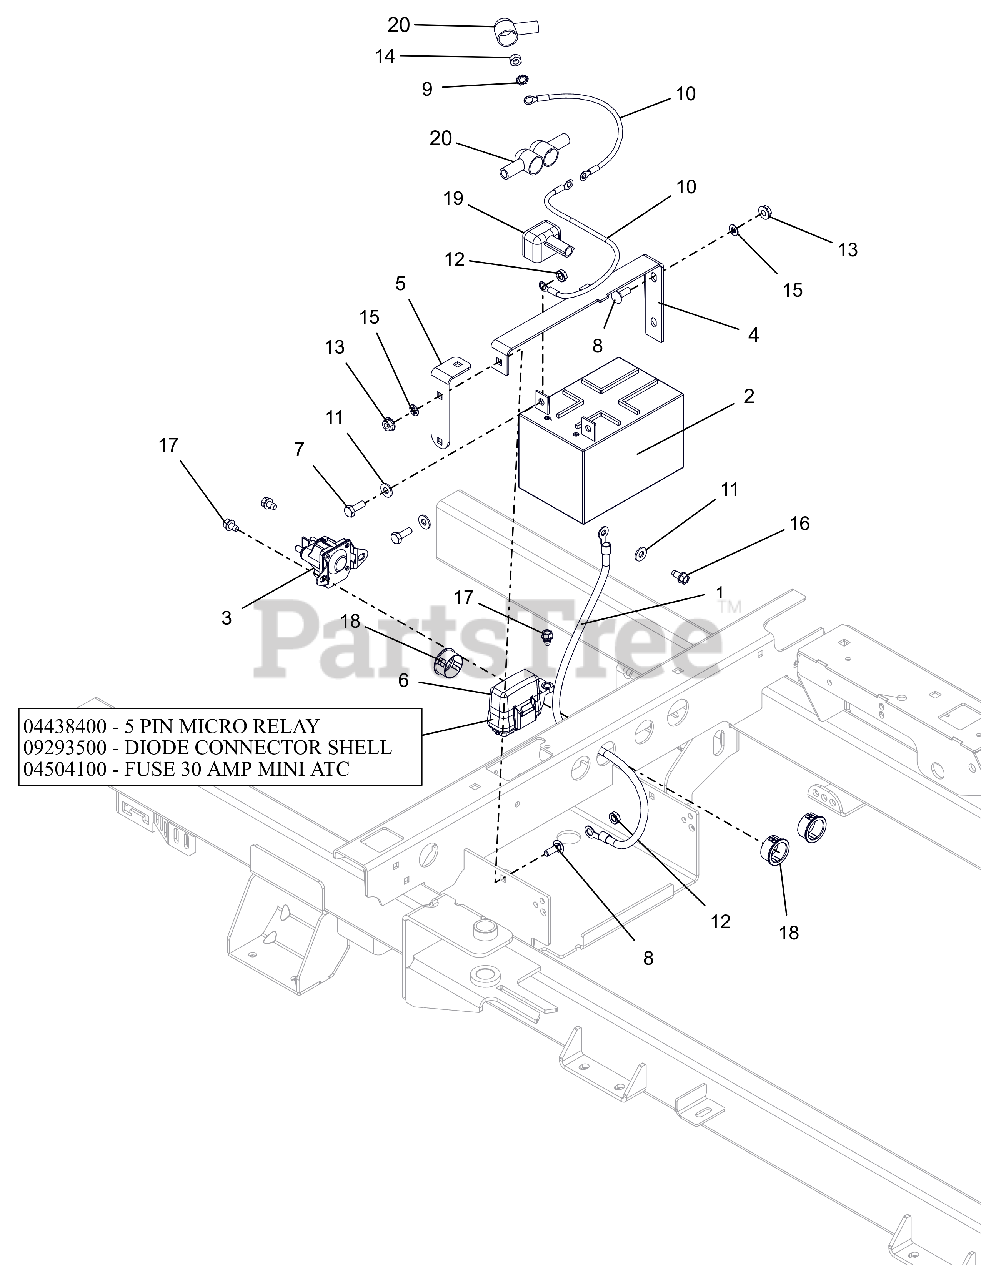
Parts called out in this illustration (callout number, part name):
1	CABLE-NEGATIVE BATTERY 24.00"
2	BATTERY, 12V 12A-190CCA
3	SOLENOID, STARTER (SEALED)
4	BRKT, BATTERY HOLD-DOWN
5	BRKT, BATTERY HOLD DOWN
6	HARNESS, WIRE-4POS KEY IKON/ZT
6	RELAY,MICRO5 TERML W/RESISTOR
6	DIODE, CONNECTOR SHELL
6	FUSE,30 AMP MINI-ATC
7	BLT, HEX .25-20X.75 G5 ZCC
8	BLT, RHSN .25-20X.750 G5 ZCC
9	WSHR,LK-EXT.262X.502X.026 ZCC
10	CABLE,POS W/2 1/4 RING 15.0 LG
11	WSHR,FLT .281X.625X.065 ZCC
12	NUT-KEPS .250-20 ZCC
13	NUT-LK-TOP-FLG .250-20 GF ZCC
14	NUT-STD .250-20 G2 ZCC
15	NUT-PUSH .25X.50 O.D.
16	SCR-TAP .25-20X.50 HWH ZCC
17	SCR,TAP .25-20X.375 HWH TR ZCC
18	BSHG, PANEL SNAP .937X1.11X.56
19	INSULATOR
20	BOOT, EYELET TERMINAL
